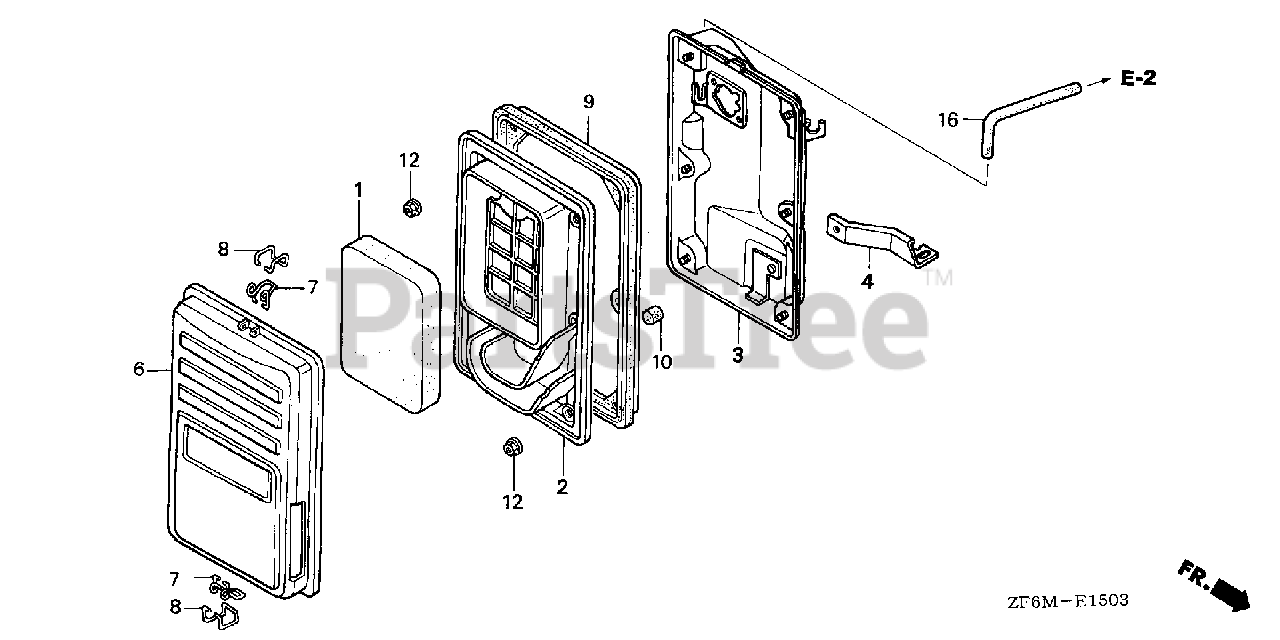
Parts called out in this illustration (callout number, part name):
1	ELEMENT, AIR CLEANER
2	SEPARATOR, AIR CLEANER
3	HOUSING, AIR CLEANER
4	STAY, AIR CLEANER
6	COVER, AIR CLEANER
7	CLIP A, AIR CLEANER WIRE
8	CLIP B, AIR CLEANER WIRE
9	SEAL, AIR CLEANER
10	FILTER, DRAIN TUBE
12	NUT, FLANGE (5MM)
16	TUBE, BREATHER
